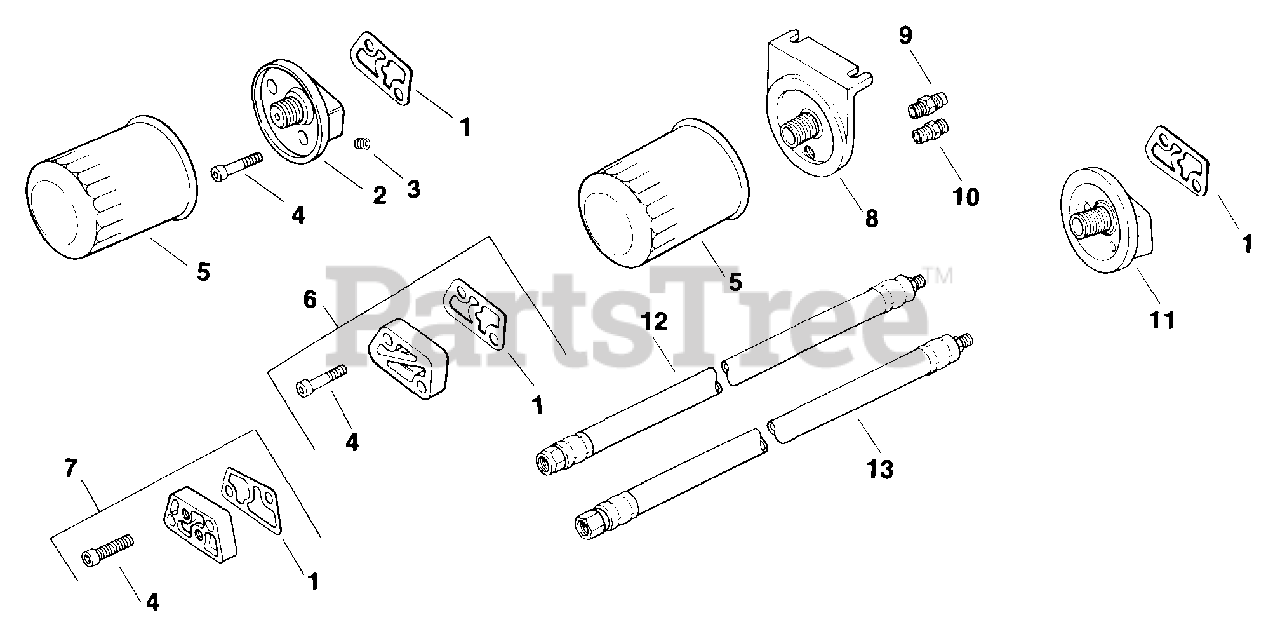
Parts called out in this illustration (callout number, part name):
2	KIT - USE 82 755 23
3	PLUG, CTSK PIPE 1/8" USE 25 139 60-S
4	SCREW, HEX SOCKET HEAD CAP USE 25 086 89-S
5	FILTER, OIL
